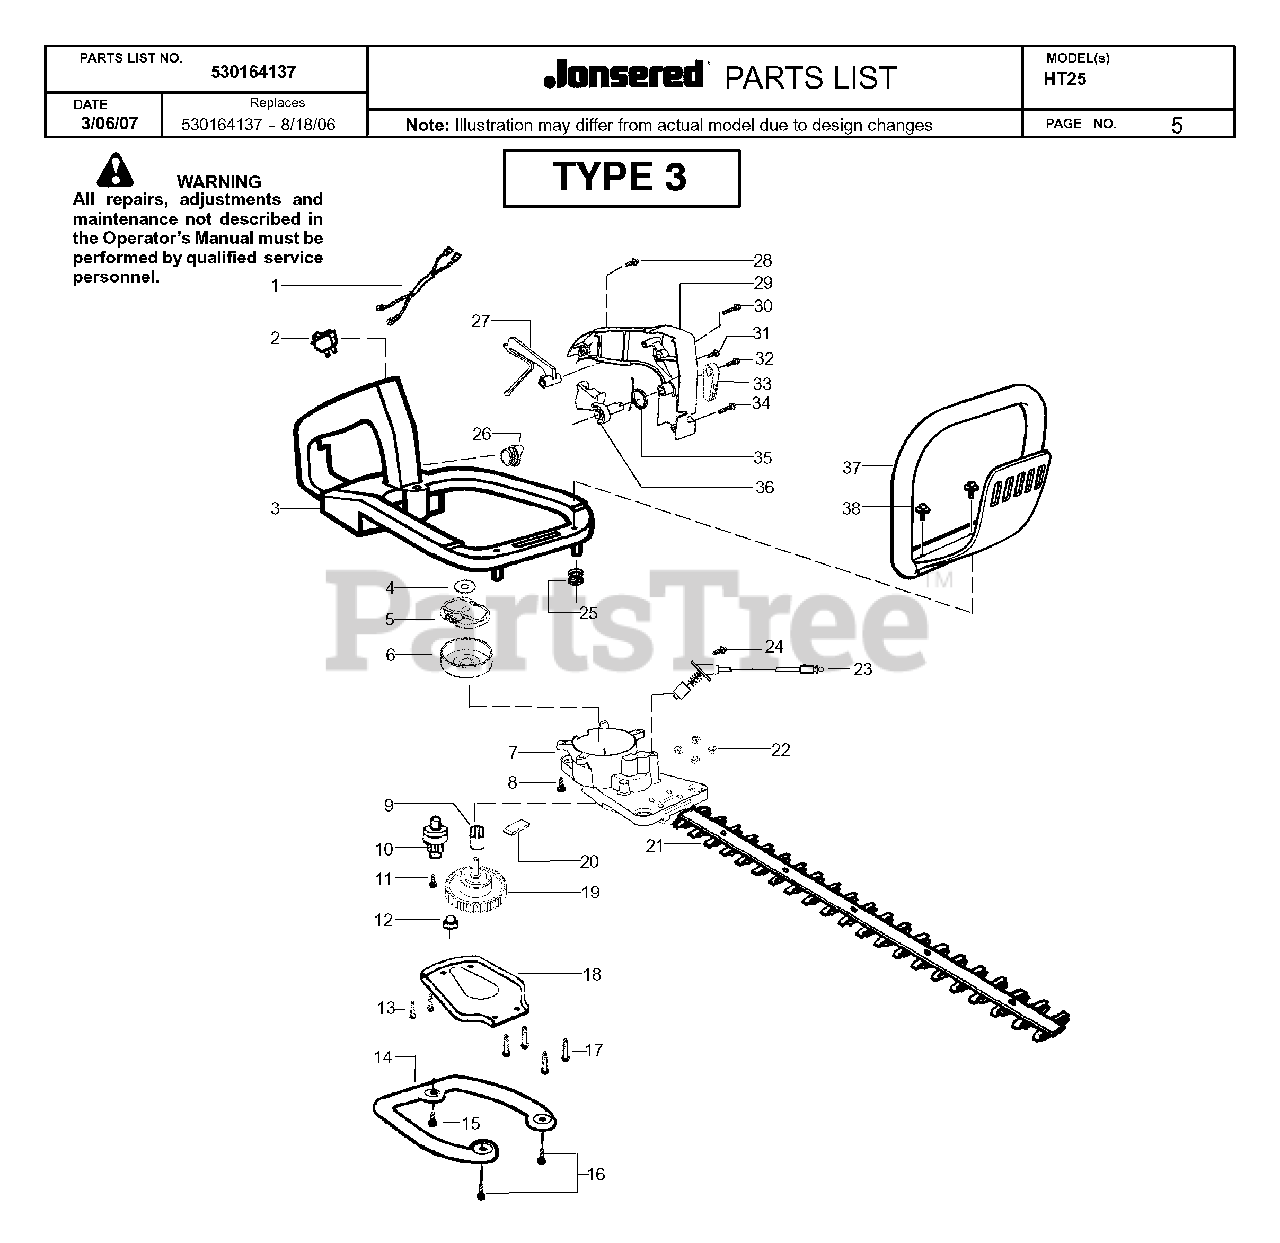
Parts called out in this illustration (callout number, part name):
4	FRICTION DISC,CLUTCH 36/41
5	CLUTCH ASSY
6	CLUTCH DRUM
8	SCREW-10-14 X 13/16 (PL
11	SCREW-10-16 X 1/2, TYPE 2
12	BLADE BUSHING
14	ISOLATOR PLATE
18	PLATE-GEARBOX COVER
21	BLADE ASSEMBLY
25	ANTIVIBE MOUNT
26	FUEL CAP ASSY W/RET.
32	SCREW 8-16 X 9/16 (PLAS
34	SCREW #10 PLASTITE 1.362
